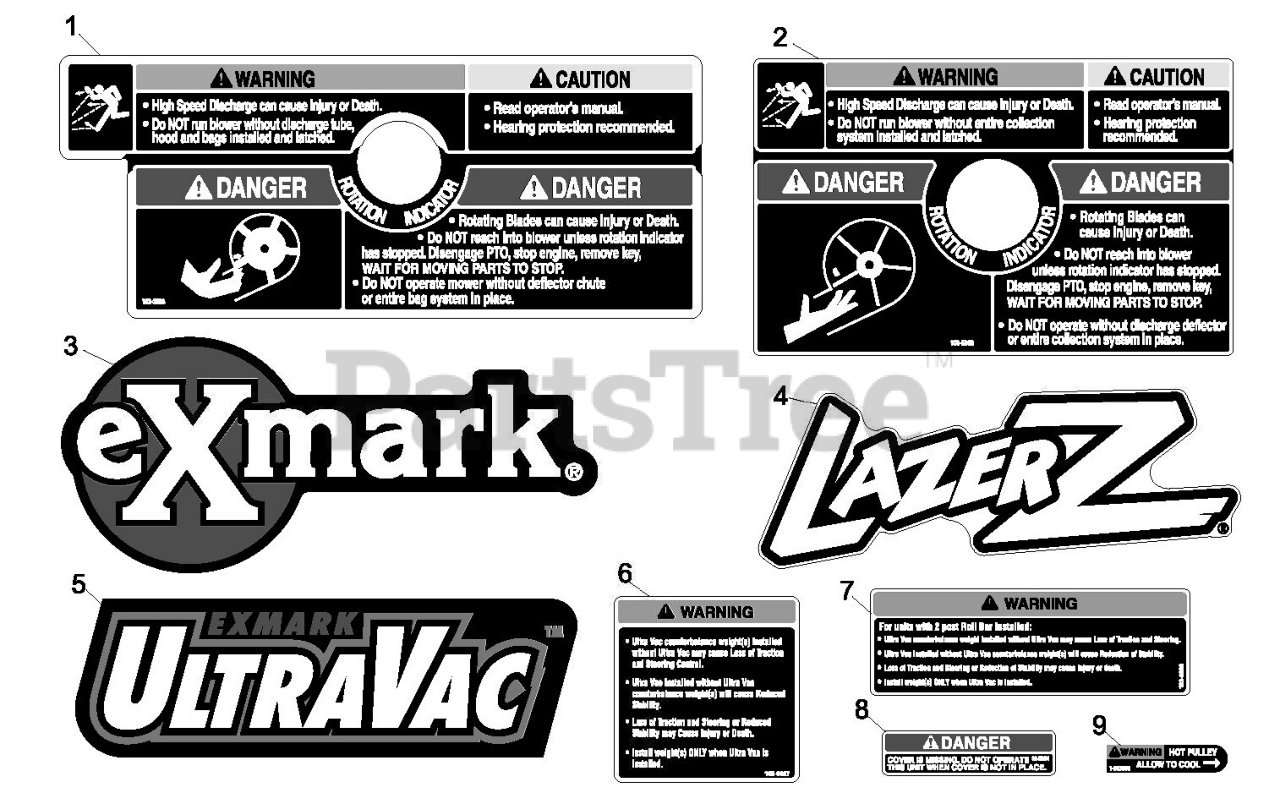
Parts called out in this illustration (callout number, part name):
1	DECAL-WARNING
2	DECAL-WARNING, BLOWER
3	DECAL, EXMARK LOGO
4	DECAL,LAZER MODEL
5	DECAL, ULTRAVAC
6	DECAL,WEIGHT
7	DECAL,WEIGHT
8	DECAL-COVER, MISSING
9	DECAL-WARNING
